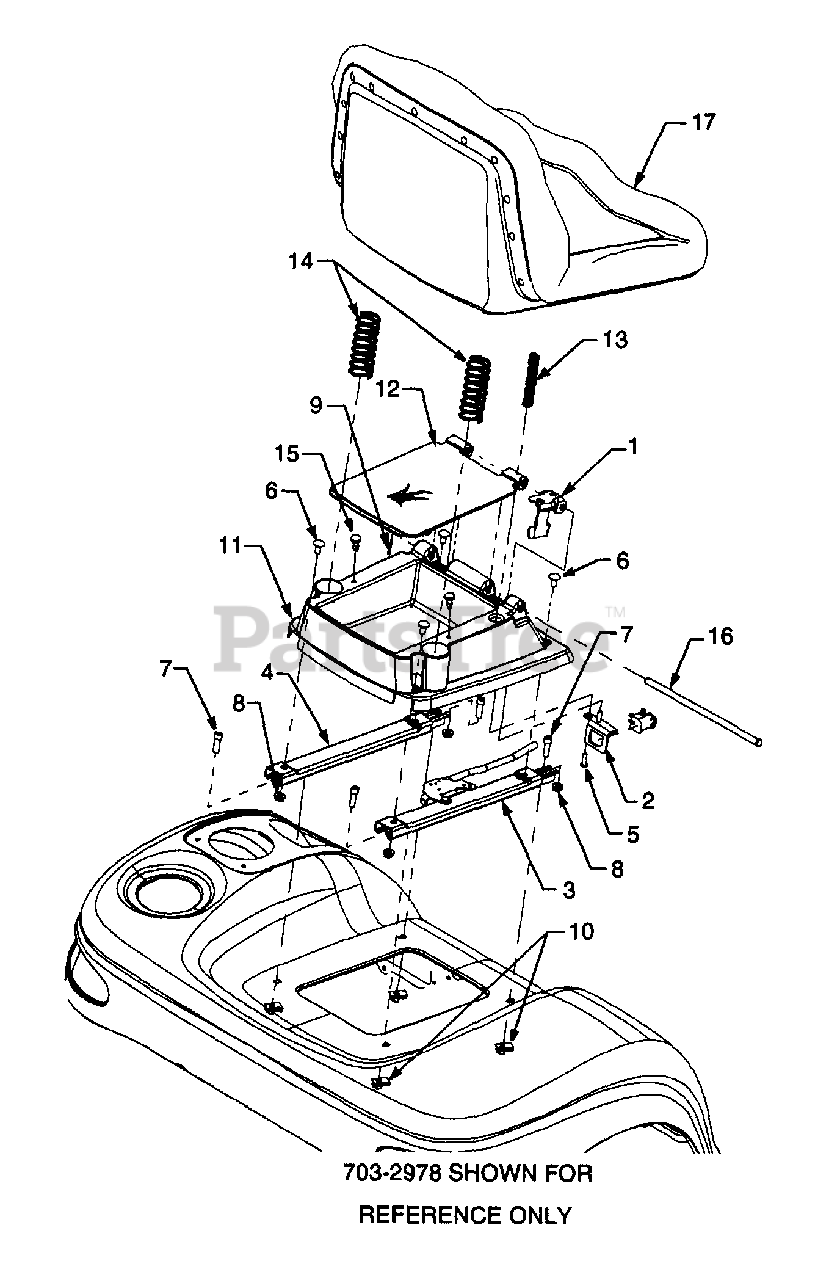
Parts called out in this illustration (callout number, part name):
1	Bracket, Seat Switch
2	Bracket, Switch Mounting
3	Track, Seat, w/Latch
4	Track, Seat, w/o Latch
5	Screw, Pan Torx Hd., #12-14 x .5
6	Carriage Bolt, 5/16-18 x .62
7	Screw, Pan Torx Hd. 5/16-18 x 1.0
8	Nut, Hex Flange Lock, 5/16-18
9	Pin, Cotter, 3/32 x .75
10	Speed Nut, U-Type, 5/16-18
11	Base, Seat
12	Lid, Tlbx
13	Spring, Compression
14	Spring, Compression
15	Bumper
16	Rod, Seat Pivot
17	Seat, High Back
